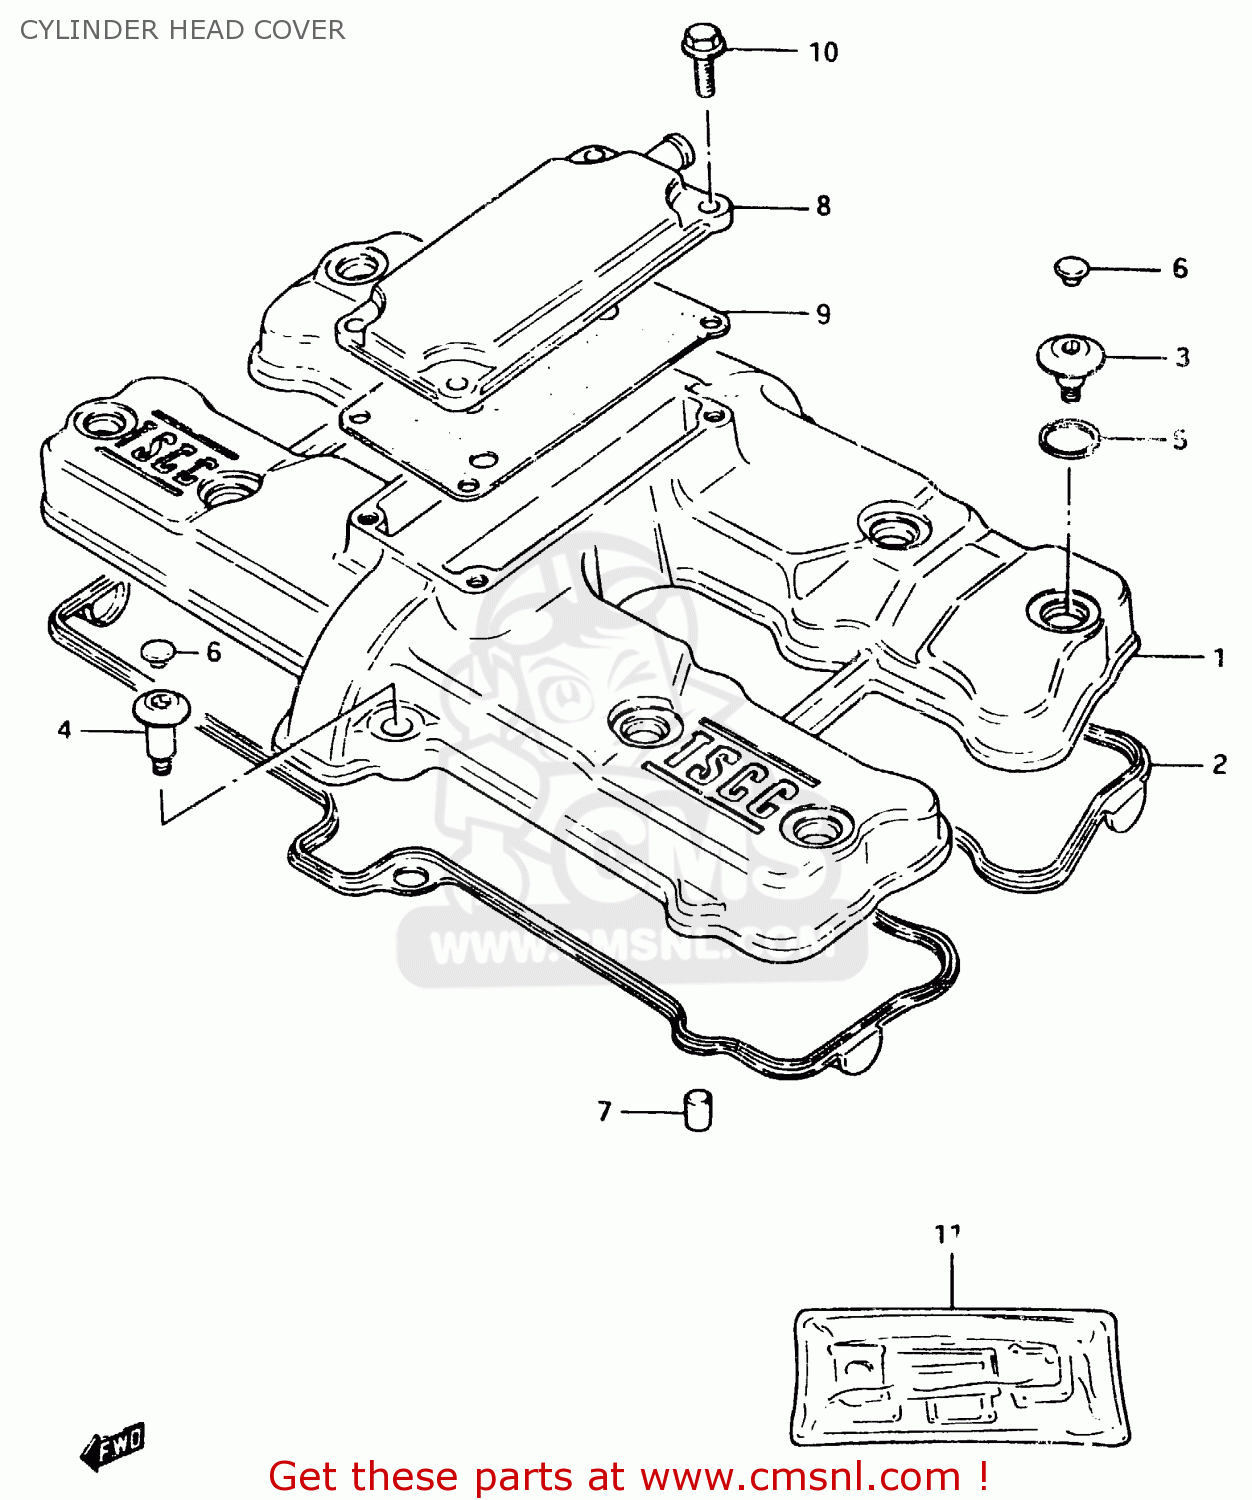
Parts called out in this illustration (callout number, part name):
1	COVER,CYLINDER HEAD
2	GASKET,HEAD COVER (NAS)
3	BOLT(7X5.5)
4	BOLT(7X19)
5	WASHER
6	CAP(OD:10)
7	PIN
8	COVER,BREATHER
9	GASKET (MCA)
10	BOLT
11	GASKET SET
